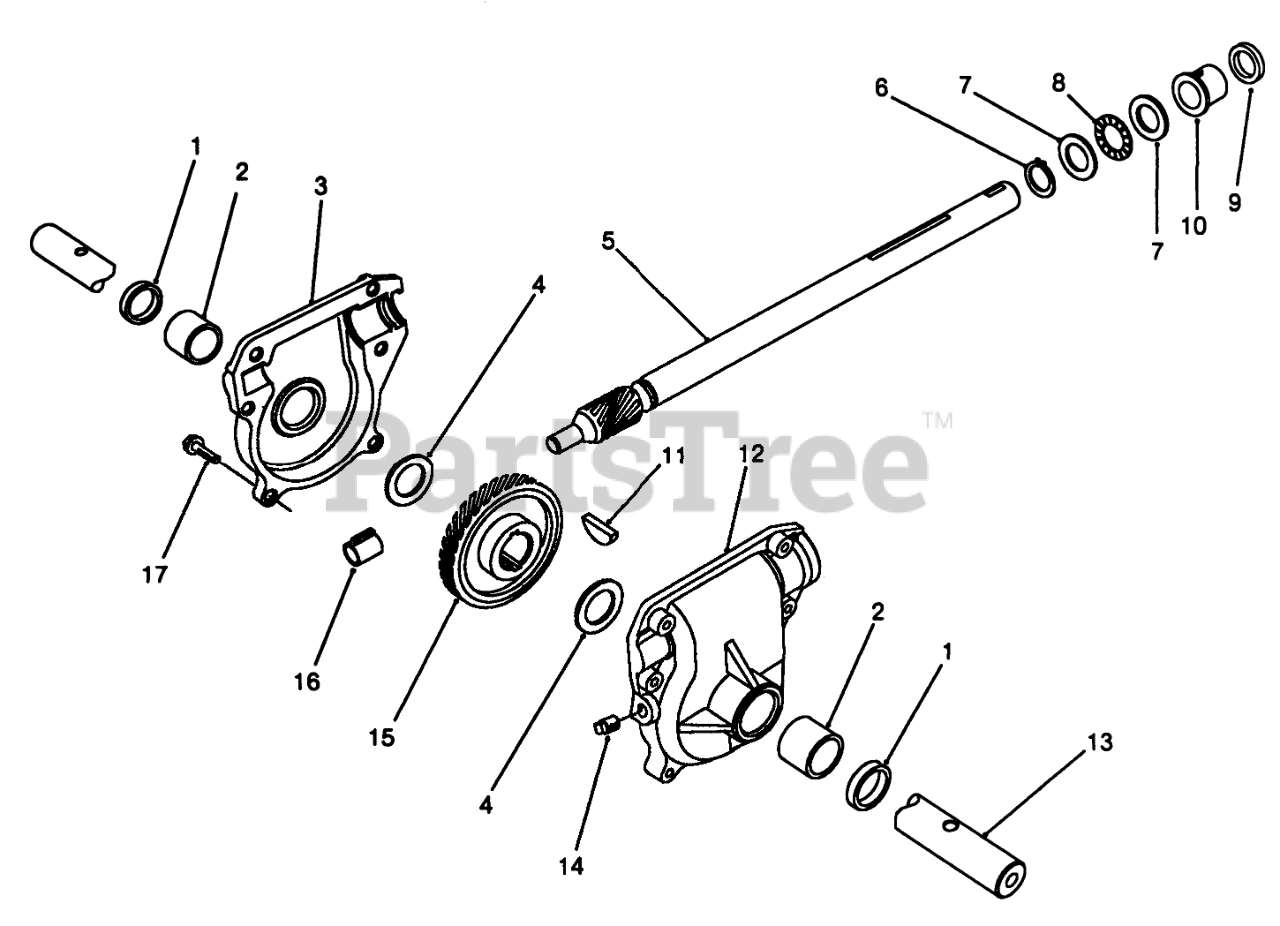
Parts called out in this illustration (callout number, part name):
1	SEAL-OIL
2	BUSHING
3	Gearcase Assembly-R.H. (Incl. Ref. #1-2)
4	WASHER-THRUST
5	Shaft-Impeller
6	RING-RETAINING, Ext
7	WASHER-THRUST
8	BEARING-THRUST
9	SEAL-OIL
10	BUSHING-INPUT
11	KEY-WOODRUFF
12	Gearcase Assembly-L.H. (Incl. Ref. #1-2)
13	SHAFT-AUGER
14	PLUG-PIPE, SQH
15	GEAR-HELICAL
16	BUSHING-WORM
